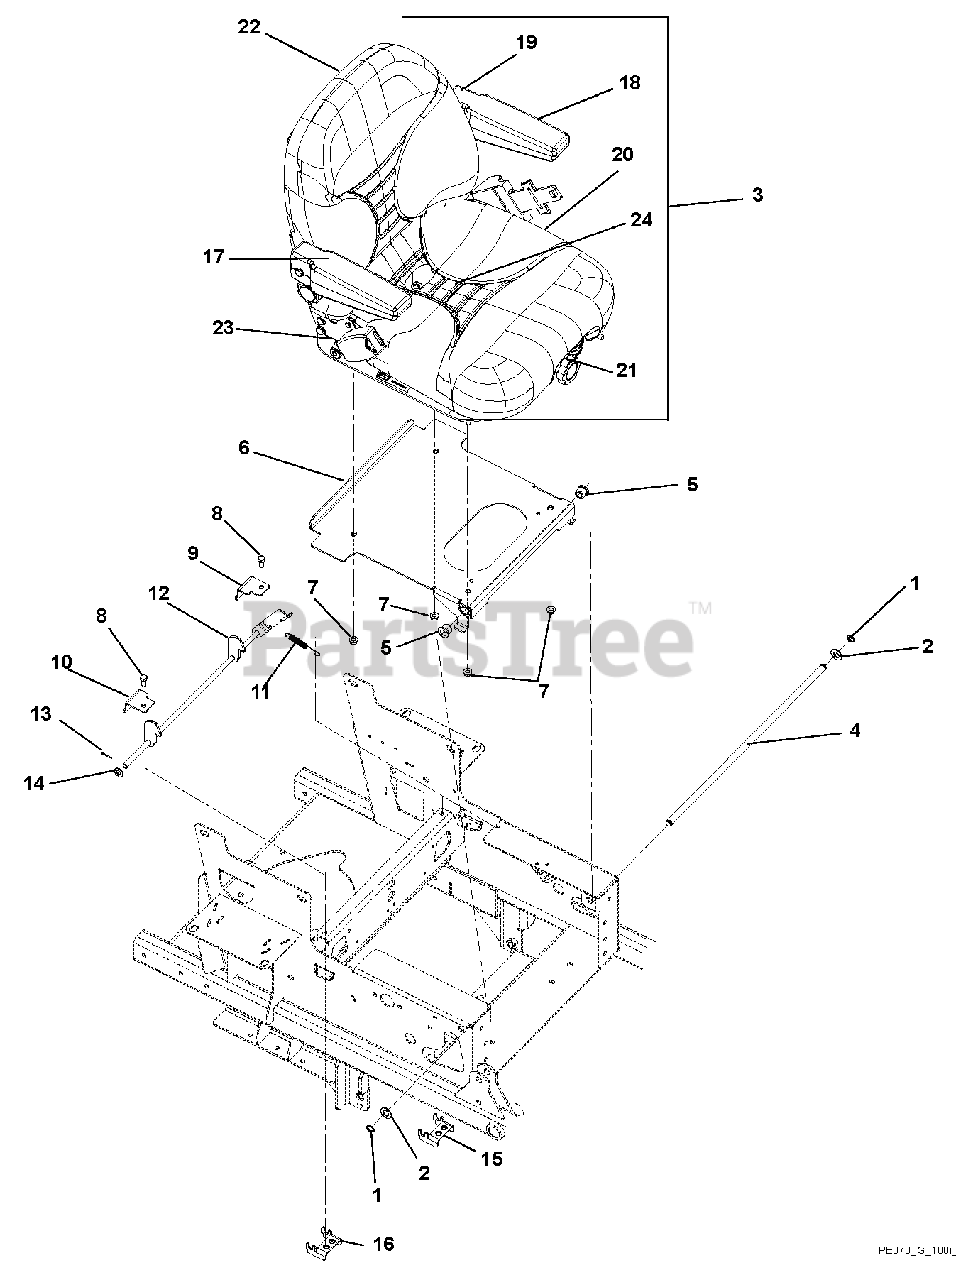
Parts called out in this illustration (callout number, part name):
1	Ring, Retaining External .500 x .050
2	Washer, Flat Steel .531 x 1.00 x .063
3	Seat, Suspension – with Belt, Light Gray
4	Shaft, 100I Seat Pivot
5	Bushing, Flange .516 x .750 x .625 x .937
6	Seat Plate Weldment
7	Nut, Locking Top Flange .31-18
8	Bolt, Hex .31-18 x .75
9	Pro-Turn 100 Left Hand Top Seat Latch Mount
10	Pro-Turn 100 Right Hand Top Seat Latch Mount
11	Spring, Tension .043 x .44 x 3.31
12	Pro-Turn 100 Seat Latch Weldment
13	Pin, Center .09 x .75 Extended Prong Square Cut
14	Washer, Flat Steel .406 x .812 x .065
15	Pro-Turn 100 Right Hand Seat Latch Mount Weldment
16	Pro-Turn 100 Left Hand Seat Latch Mount Weldment
17	Kit, Right Hand Armrest Assembly
18	Kit, Left Hand Armrest Assembly
19	Kit, Back Cushion, Light Grey
20	Kit, Seat Cushion, Light Grey
21	Kit, Seat Knobs
22	Kit, Seat Back
23	Kit, Seat Slides
24	Kit, Seat Spring and Saddle
